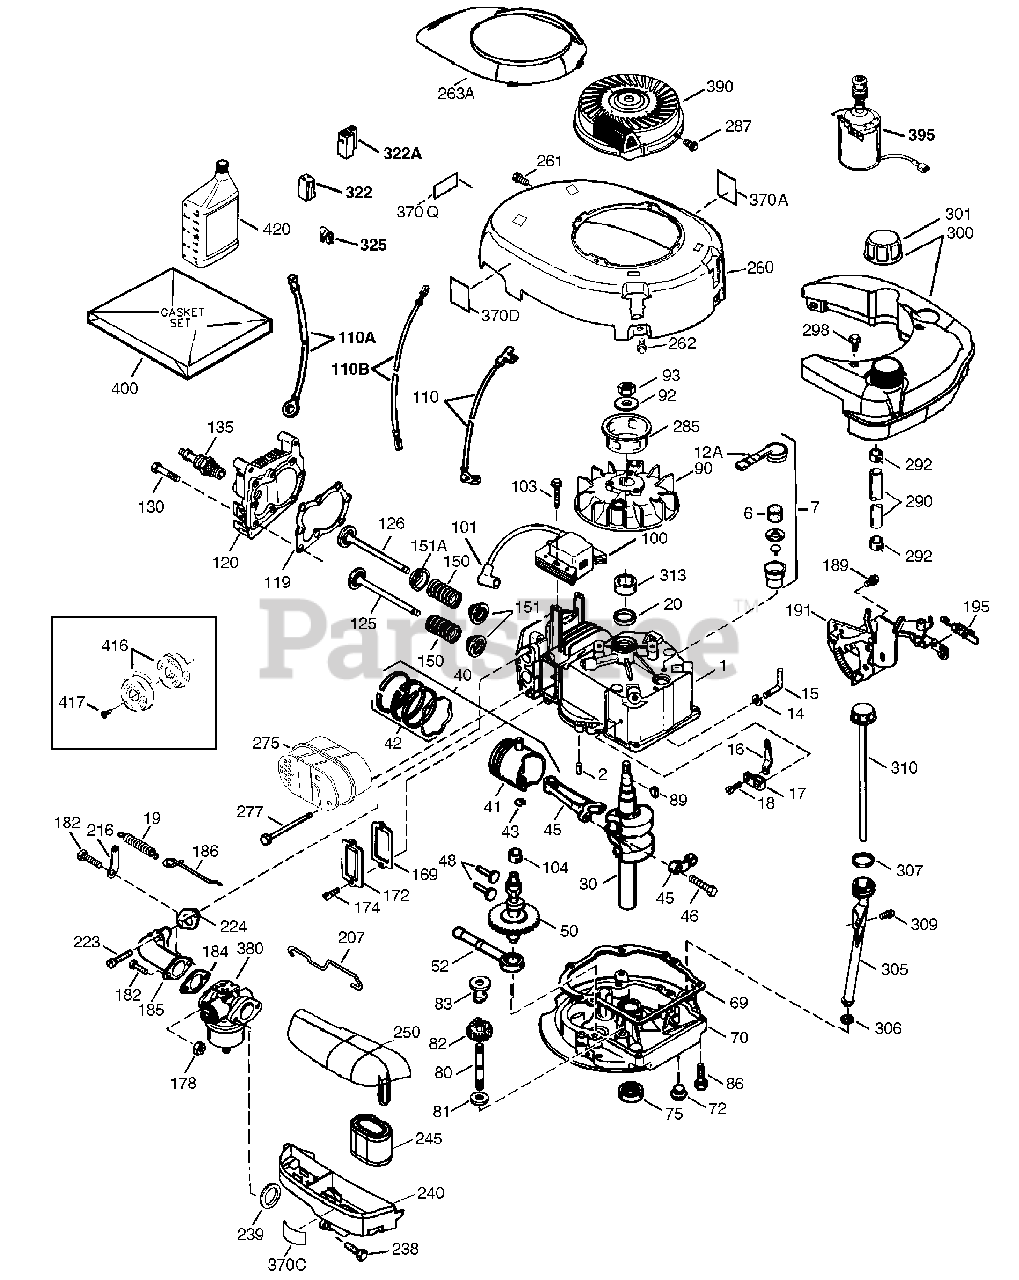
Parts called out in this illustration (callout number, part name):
1	Cylinder (Incl. 2,20 & 150)
2	Dowel Pin
6	Breather Element
7	Breather Body ASM(Incl. 6 & 12A)
12A	Breather Cover & Tube
14	Washer
15	Governor Rod(Incl. 14)
16	Governor Lever
17	Governor Lever Clamp
18	Screw, Torx T-15
19	Extension Spring
20	Oil Seal
30	Crankshaft
40	Piston, Pin & Ring Set(Std.)
40	Piston, Pin & Ring Set(.010" OS)
41	Piston & Pin ASM(Std.)(Incl. 43)
41	Piston & Pin ASM(.010" OS)(Incl. 43)
42	Ring Set (Std.)
42	Ring Set (.010" OS)
43	Piston Pin RetainingRing
45	Connecting Rod ASM(Incl. 46)
46	Connecting Rod Bolt
48	Valve Lifter
50	Camshaft
52	Oil Pump ASM
69	Mounting FlangeGasket
70	Mounting Flange(Incl. 72 thru 83, 306)
72	Oil Drain Plug
75	Oil Seal
80	Governor Shaft
81	Washer
82	Governor Gear ASM(Incl. 81)
83	Governor Spool
86	Screw
89	Flywheel Key
90	Flywheel
92	Belleville Washer
93	Flywheel Nut
100	Solid State Ignition
101	Spark Plug Cover
103	Screw, Torx T-15
104	Cam Bushing
110	Ground Wire
110A	Wiire ASM
110B	Wiire ASM
119	Cylinder Head Gasket
120	Cylinder Head
125	Exhaust Valve (Std.)(Incl. 151)
126	Intake Valve (Std.)(Incl. 151)
130	Screw
135	Resistor Spark Plug(RJ19LM)
150	Valve Spring
151	Valve Spring Cap
151A	Intake Valve Seal
169	Valve Cover Gasket
172	Valve Cover
174	Screw
178	Nut & Lock Washer
182	Screw
184	Carburetor To IntakePipe Gasket
185	Intake Pipe
186	Governor Link
189	Screw
191	S.E. Brake Bracket(Incl. 195)
195	Terminal
207	Throttle Link
216	R.P.M. Adjusting Lever
223	Screw
224	Intake Pipe Gasket
238	Screw
239	Air Cleaner Gasket
240	Air Cleaner Body
245	Air Cleaner Filter
250	Air Cleaner Cover
260	Blower Housing
261	Screw
262	Screw
263A	Starter Grill
275	Muffler
277	Screw
285	Starter Cup
287	Screw
290	Fuel Line
292	Fuel Line Clamp
298	Screw
300	Fuel Tank(Incl. 292 & 301)
301	Fuel Cap
305	Oil Fill Tube
306	"O"-Ring
307	"O"-Ring
309	Screw
310	Dipstick
313	Spacer
322	Body Connector
322A	Body Connector
325	Spring Clip
370A	Lubrication Decal
370C	Primer Decal (3X)
370D	Caution Decal
370Q	Emissions Decal
380	Carburetor (Incl. 184)
390	Rewind Starter
400	Gasket Set
416	Spark Arrestor Kit
417	Screw
420	SAE30 4-Cycle Engine Oil (Quart)
